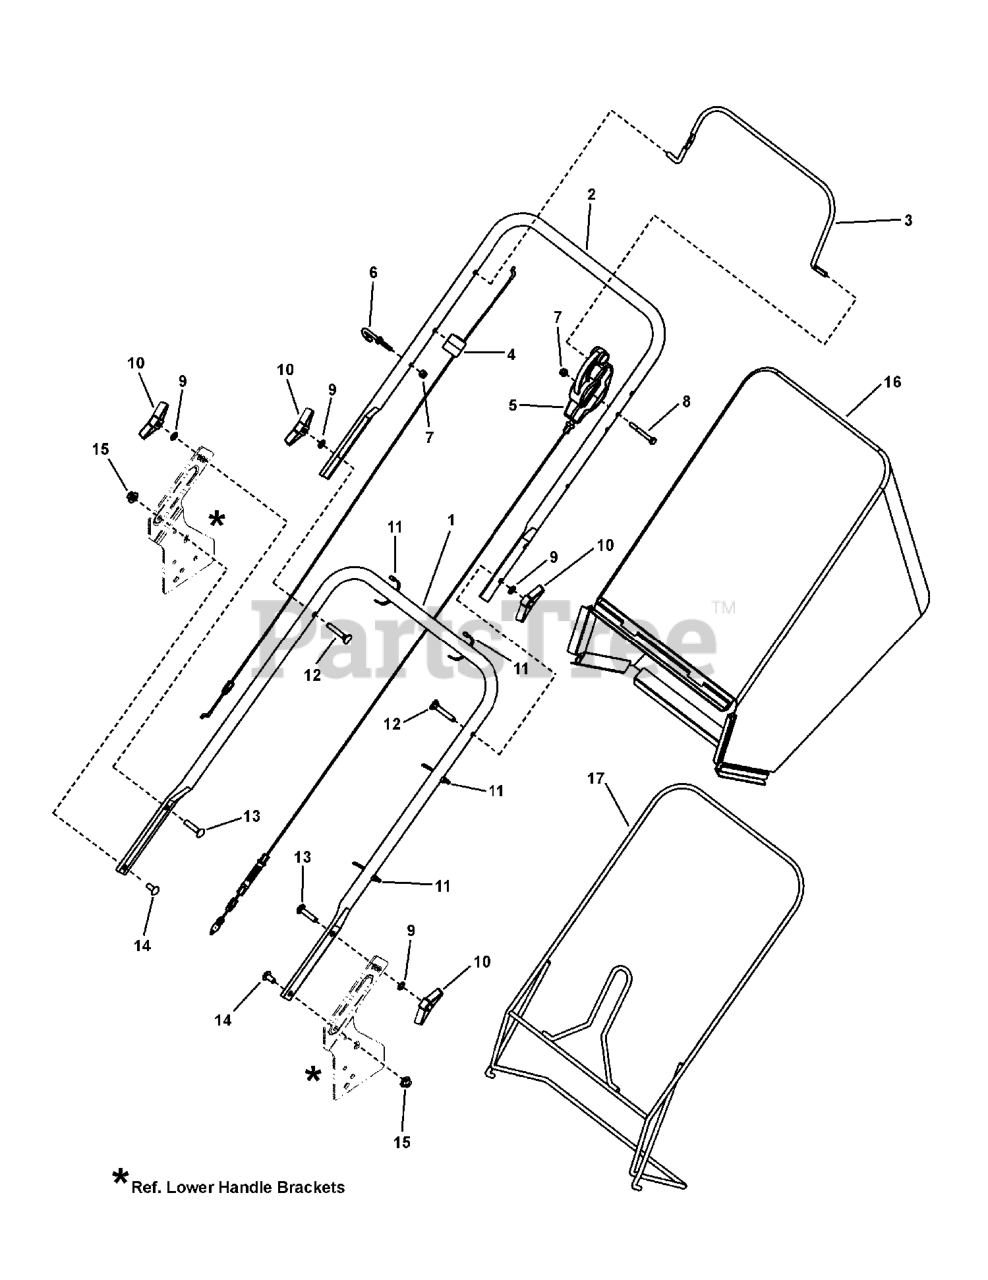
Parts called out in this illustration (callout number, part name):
1	HANDLE, Lower
2	HANDLE, Upper, Propelled
3	BAIL, OPC Propelled
4	CABLE, Bail
5	CONTROL, Drive, Single Speed
6	GUIDE, Rope (1/4-20 thread)
7	NUT,1/4-20 Hex Nyloc
8	SCREW, 1/4-20 x 2-1/4" Hex Head Cap, GR 5
9	WASHER, 5/16" Internal Tooth Lock
10	KNOB, 5/16-18 Wing Nut
11	WIRE TIE, 11 Inch Std Black Nylon
12	BOLT, 5/16-18 x 2" Curved Head Square Neck, GR 2
13	BOLT, 5/16-18 x 1-1/2" Round Head Short Square Neck GR 5
14	BOLT, 5/16-18 x 3/4" Round Head Short Square Neck, GR 5
15	NUT, 5/16-18 Large Head Center Lock
16	GRASS BAG, 22" Rear Discharge
17	BAG FRAME, 22" WBM
